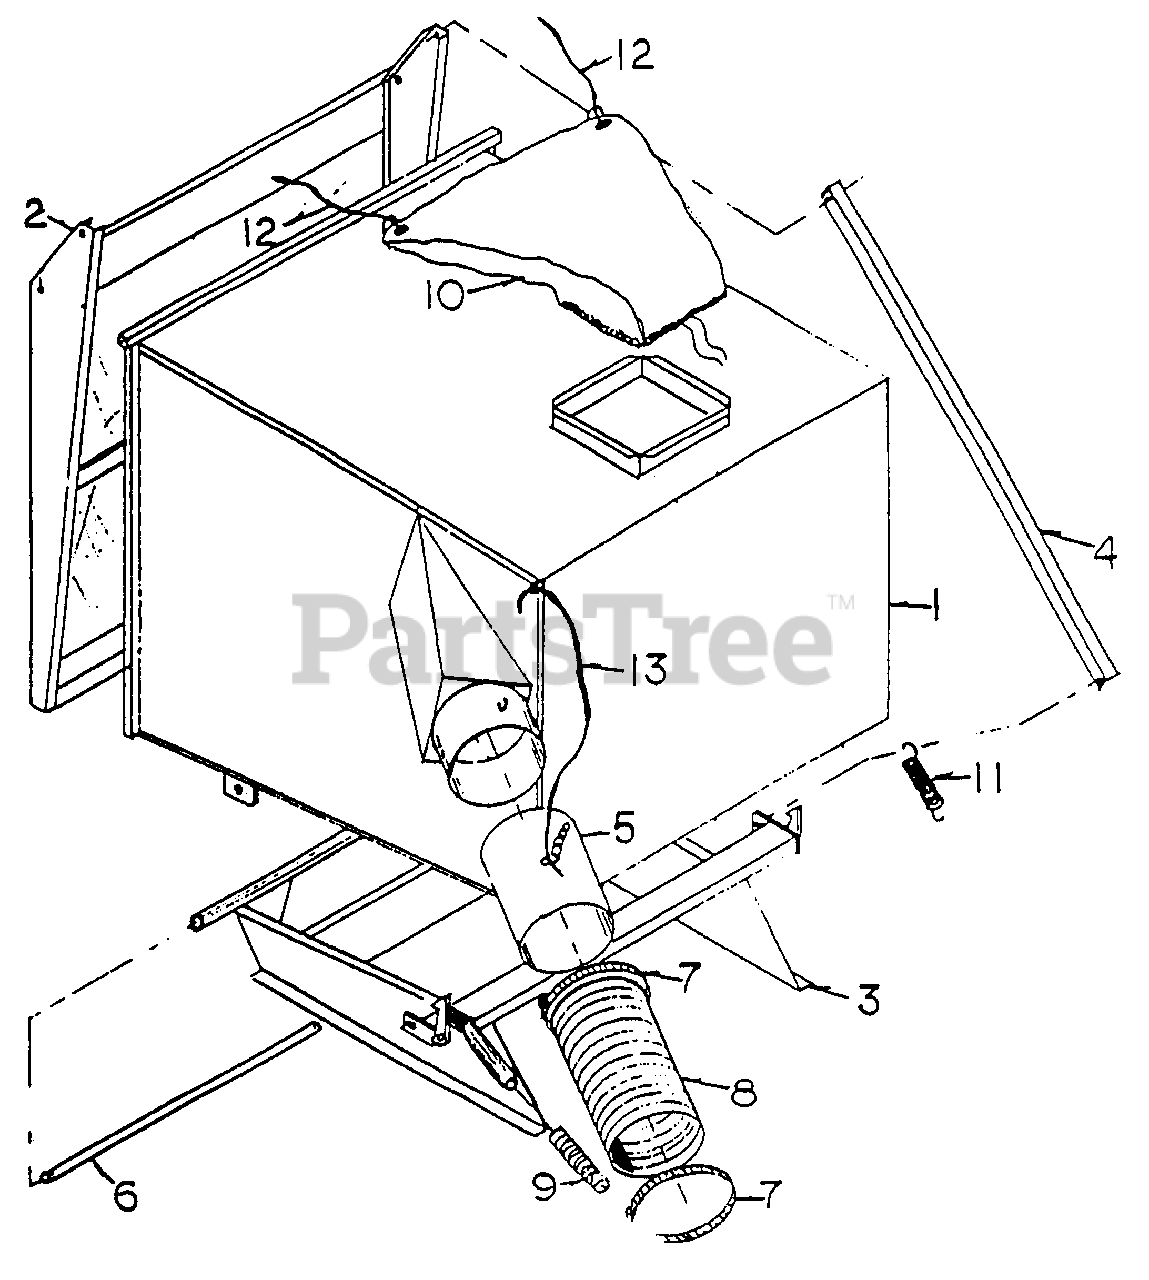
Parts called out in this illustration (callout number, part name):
1	CROSS BOx
3	DOx MOUNT
4	DOOR LINKAGE
5	MALE TUBE
8	HOSE
9	HANDLE GRIP
12	BAG ROPE
13	MALE TUBE ROPE
